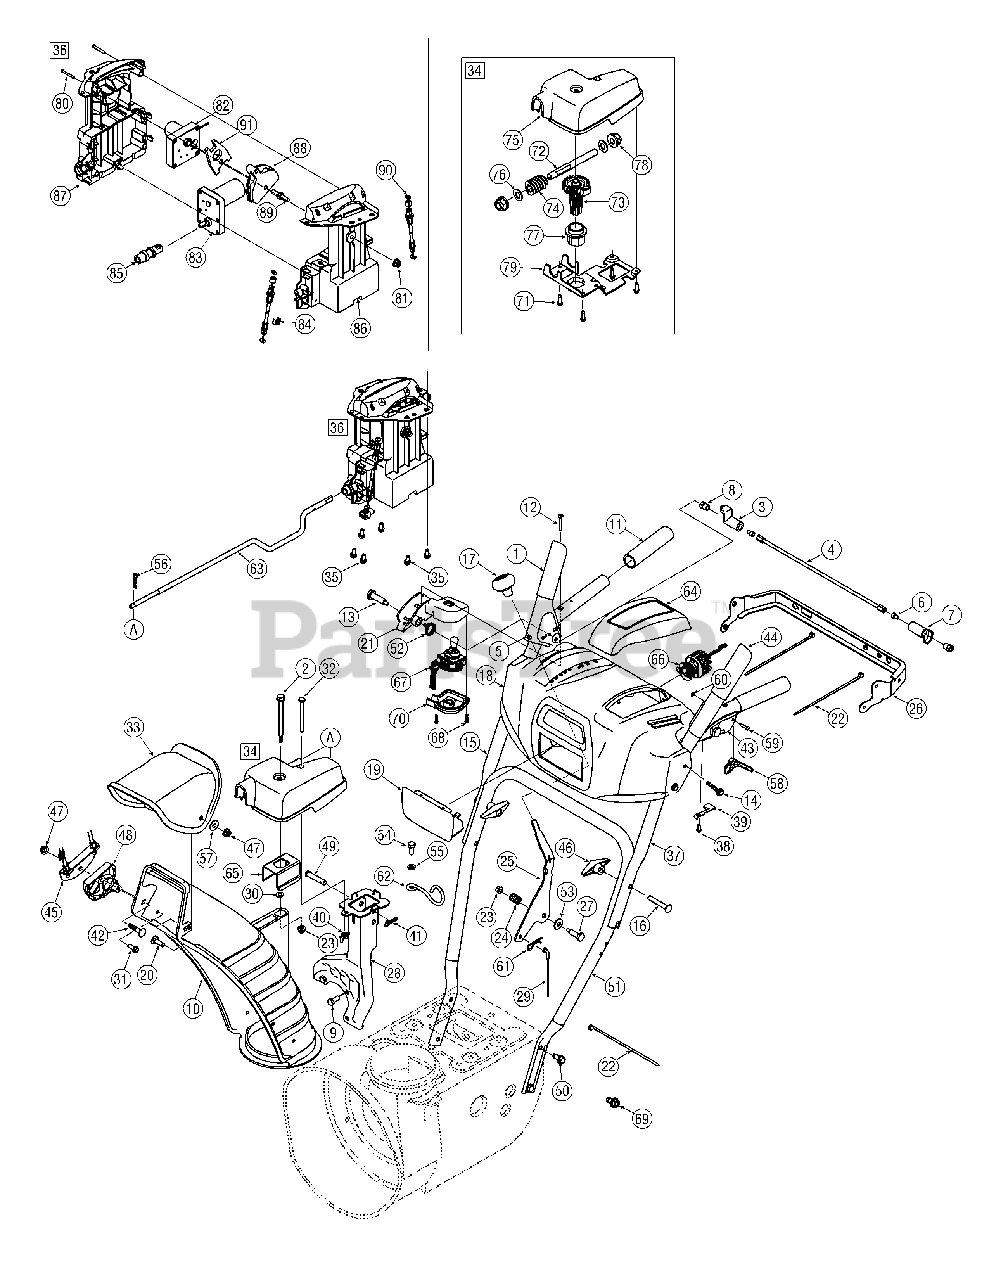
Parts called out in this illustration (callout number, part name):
1	Handle Engagement Assembly RH
2	Flange Shoulder Screw
3	Lock Plate
4	Pivot Rod
5	Rubber Bumper
6	Screw, 1/4-20 x .500
7	Clutch Lock Cam
8	Shoulder Nut, 1/4-20
9	Hex Screw, 5/16-24 x .750
10	Lower Chute
12	Screw, #10-24 x 0.375
13	Shoulder Screw, 1/4-20
14	Screw, 1/4-20 x 1.625
15	Upper Handle RH
16	Carriage Screw, 5/16-18 x 2.25
17	Shift Knob
18	Handle Panel
20	Carriage Bolt, 5/16-18 x 1.0
21	Handle Clutch Lock Assembly - RH
22	Cable Tie
23	Flange Lock Nut, 1/4-20
24	Compression Spring
25	Shift Lever
26	Panel Bracket
27	Shoulder Screw
28	Chute Support Bracket
29	Speed Selector Cable
30	Flat Washer, .25 x .630 x .0515
31	Hi-Lo Screw, 1/4-15 x .75
32	Hex Screw, 1/4-20 x 3.00
33	Upper Chute
34	Electric Chute Gearbox Assembly
35	Hi-Lo Screw, 1/4-15 x 0.5
36	Electric Chute Control Assembly
37	Upper Handle LH
38	Screw, #8-16 x 0.50
39	Clutch Lock Spring
40	Wing Nut, 1/4-20
41	Bow Tie Cotter Pin
42	Carriage Bolt, 5/16-18 x 1.50
43	Handle Clutch Lock Assembly - LH
44	Handle Engagement Assembly LH
45	Cable Bracket
46	Wing Knob
47	Flange Lock Nut, 5/16-18
48	Chute Tilt Cable Guide
49	Clevis Pin
50	Screw, 5/16-18 x 0.75
51	Lower Handle
52	Torsion Spring
53	Flat Washer
54	Screw, M8-1.25
55	Flat Washer, .330 x .630 x .0635
56	Cotter Pin
57	Flat Washer, .349 x .879 x .063
58	Steering Control
59	Pin, 3/16
60	E-Ring
61	Click Pin
62	Cable Guide
63	Chute Rod
64	Handle Panel Cover
65	Chute Bracket
66	LED Light Socket
67	Electric Chute Harness
68	Screw, .159 OD x .610
69	Screw (For ground wire)
70	Joystick Housing Cover
71	Screw, #12-16 x .75
72	Shaft, Worm Drive
73	Gear, Helical
74	Worm, 2-Start Nylon
75	Cover, Gear, Chute Control
76	Wash., Flat, .510 x 1.00 x .060
77	Bearing, Flange, 1.00 ID
78	Bearing, Flange, .50 ID
79	Brkt., Gear, Chute Rotation
80	Scr., AB, #10-16 x 1.25
81	Nut, Flglk., 5/16-18
82	Motor, Pitch, Chute
83	Motor, Rotate, Chute
84	Clip, Cable
85	Coupler, Electric Chute
86	Hsg., LH, 4-Way, Chute Control
87	Hsg., RH, 4-Way, Chute Control
88	Gde., Cbl., Chute Tilt
89	Scr., Hex, 5/16-18 x .75
90	Cbl., Snow, 4-Way, Tall Chute
91	Adpt., Pitch, Chute
